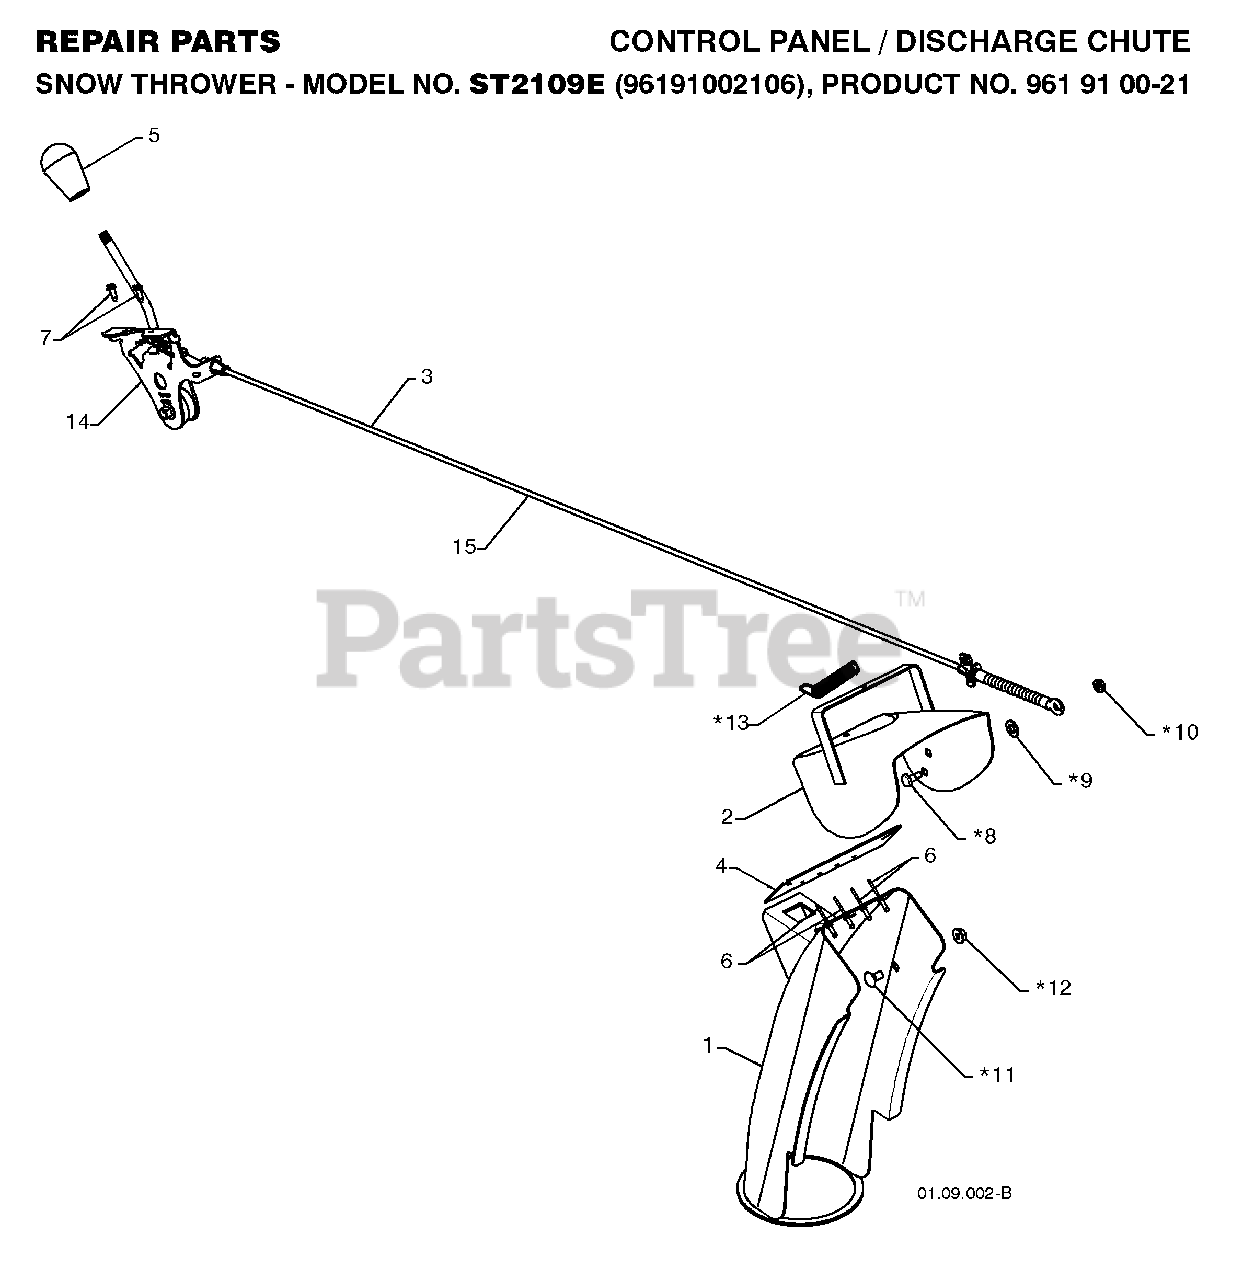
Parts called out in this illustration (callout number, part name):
3	CONTROL.ASM.DEFLECTOR
4	SEAL.DEFLECTOR
5	KNOB LEVER, BLACK
6	RIVET BLIND
7	SCREW #10-24 X 5/8
8	BOLT, SHOULDER
9	WASHER, NYLON FRICTION
10	NUT.HEX.FLANGE.1/4
11	BOLT
12	NUT, LOCK 5/16-18
14	CHUTE.DEFLECTOR.HEAD.SERVICE.
15	SERVICE.CHUTE.DEF.CBL.BLK
